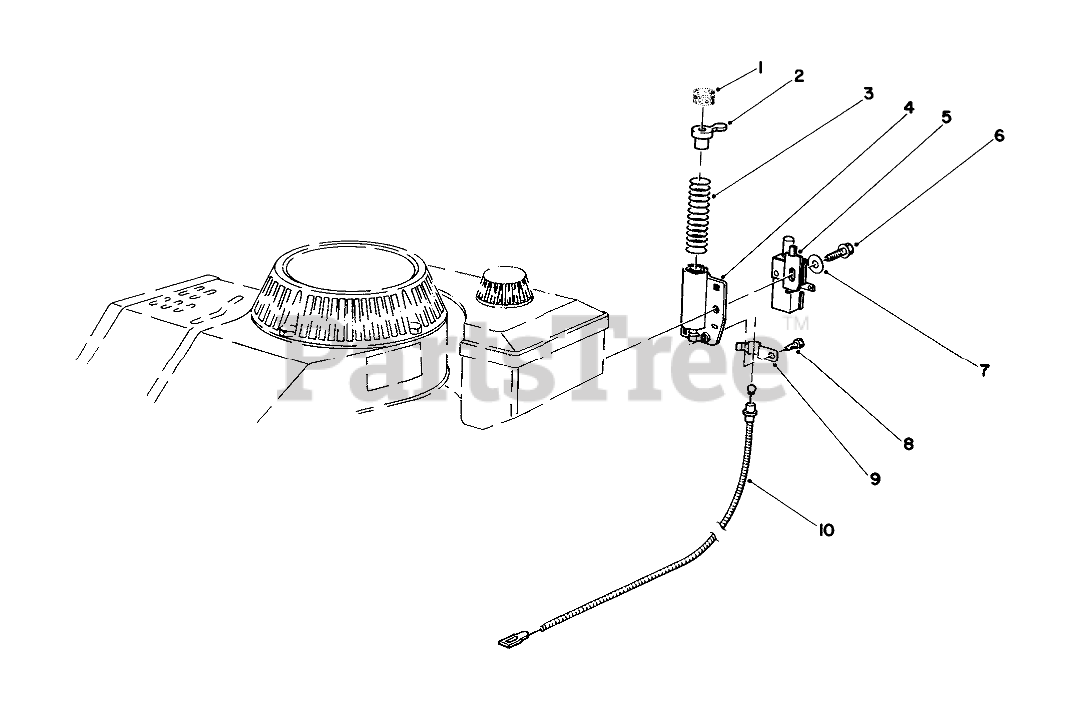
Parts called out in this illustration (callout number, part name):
1	Pad-Friction
2	Plunger & Pad Assembly (Incl. Ref. #1)
3	COMP SPRING
4	TUBE W A
5	PUSH BUTTON SWITCH
6	THO FORM SCREW M6 X 1
7	WASHER-FLAT
8	SCREW
9	CABLE CLAMP
10	BRAKE CABLE
